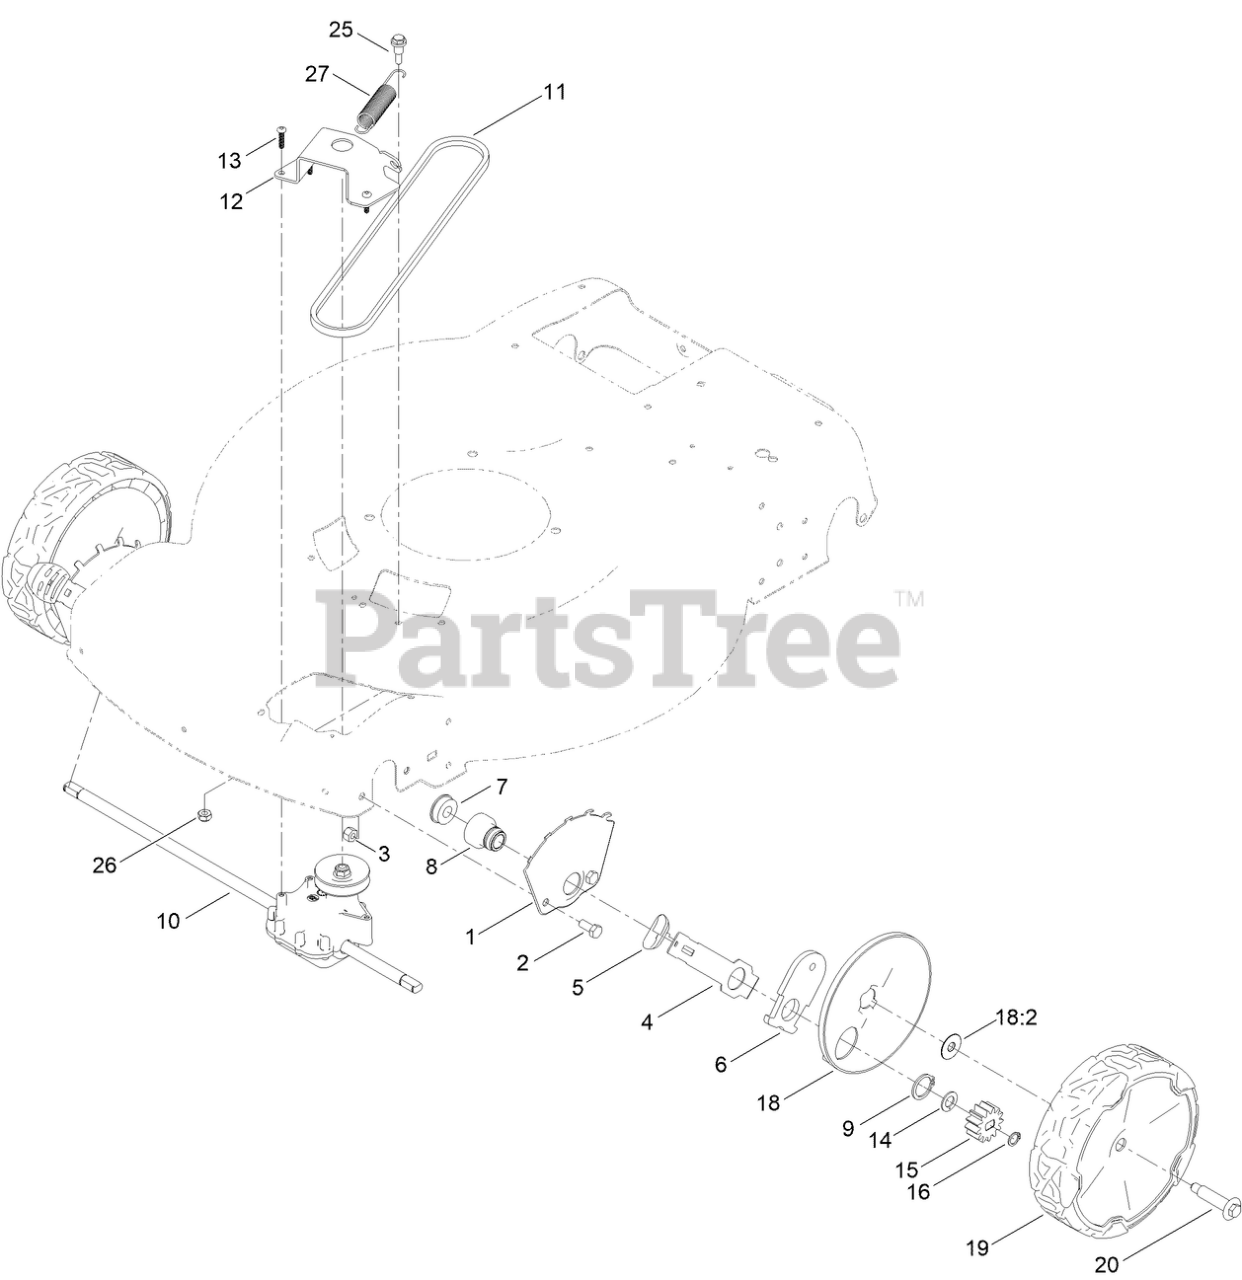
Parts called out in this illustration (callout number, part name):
1	PLATE-HOC,FRONT FSVQ WEDNESDAY
2	SCREW-HH
3	NUT-HEX
4	ARM-SPRING
5	KNOB-HOC
6	ARM-PIVOT, FRONT
7	BEARING-BALL
8	RETAINER-BEARING, HOC
9	RING-RETAINING
10	TRANSMISSION
11	V-BELT
12	BRACKET-TRANSMISSION
13	SCREW-PLASTITE
14	WASHER-THRUST
15	GEAR-PINION, 13T
16	RING-RETAINING
18	ASM-COVER, WHEEL (DK GRAY)
18:2	WASHER-STEPPED
19	ASM-8" WHEEL, FWD (BUSHINGS)
20	BOLT-SHOULDER
25	BOLT-SHOULDER
26	NUT-LOCK
27	SPRING-EXTENSION
